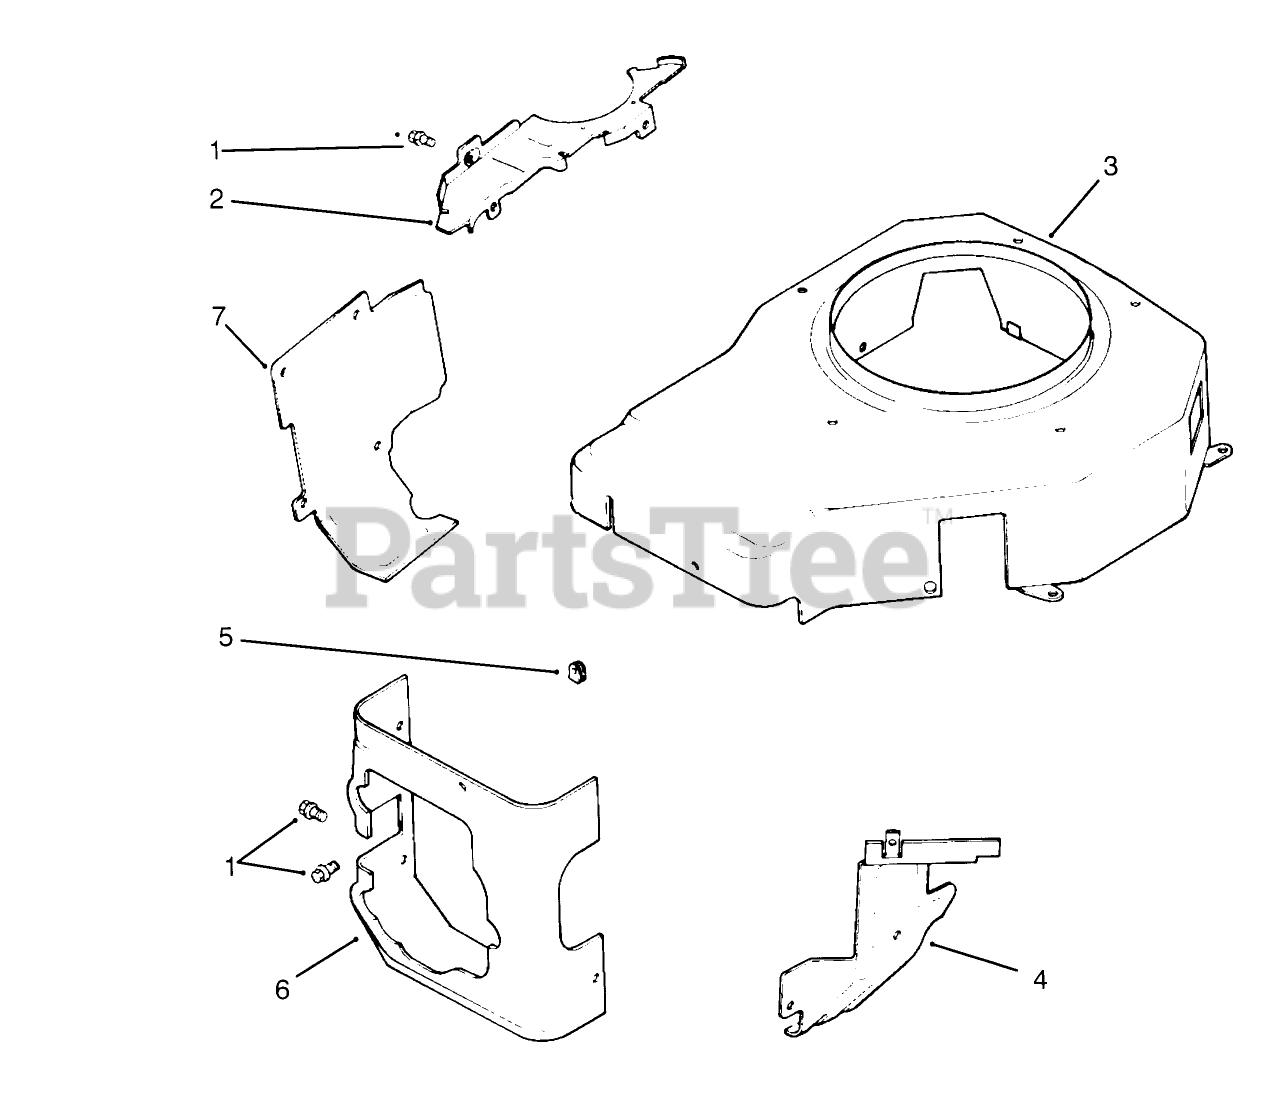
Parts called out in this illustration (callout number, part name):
2	Plate-Blower Housing (Only On: 72042,72043,72062,72063)
3	Housing-Blower (Only On: 72042,72043,72062,72063)
4	Baffle-Carburetor (Only On: 72042, 72043, 72062, 72063)
5	Grommet-Blower Housing (Only On: 72042, 72043, 72062, 72063)
6	Baffle-Cylinder Head (Only On: 72042, 72063, 72062, 72043)
7	Baffle-Cylinder Barrel (Only On: 72042, 72063, 72062, 72043)
